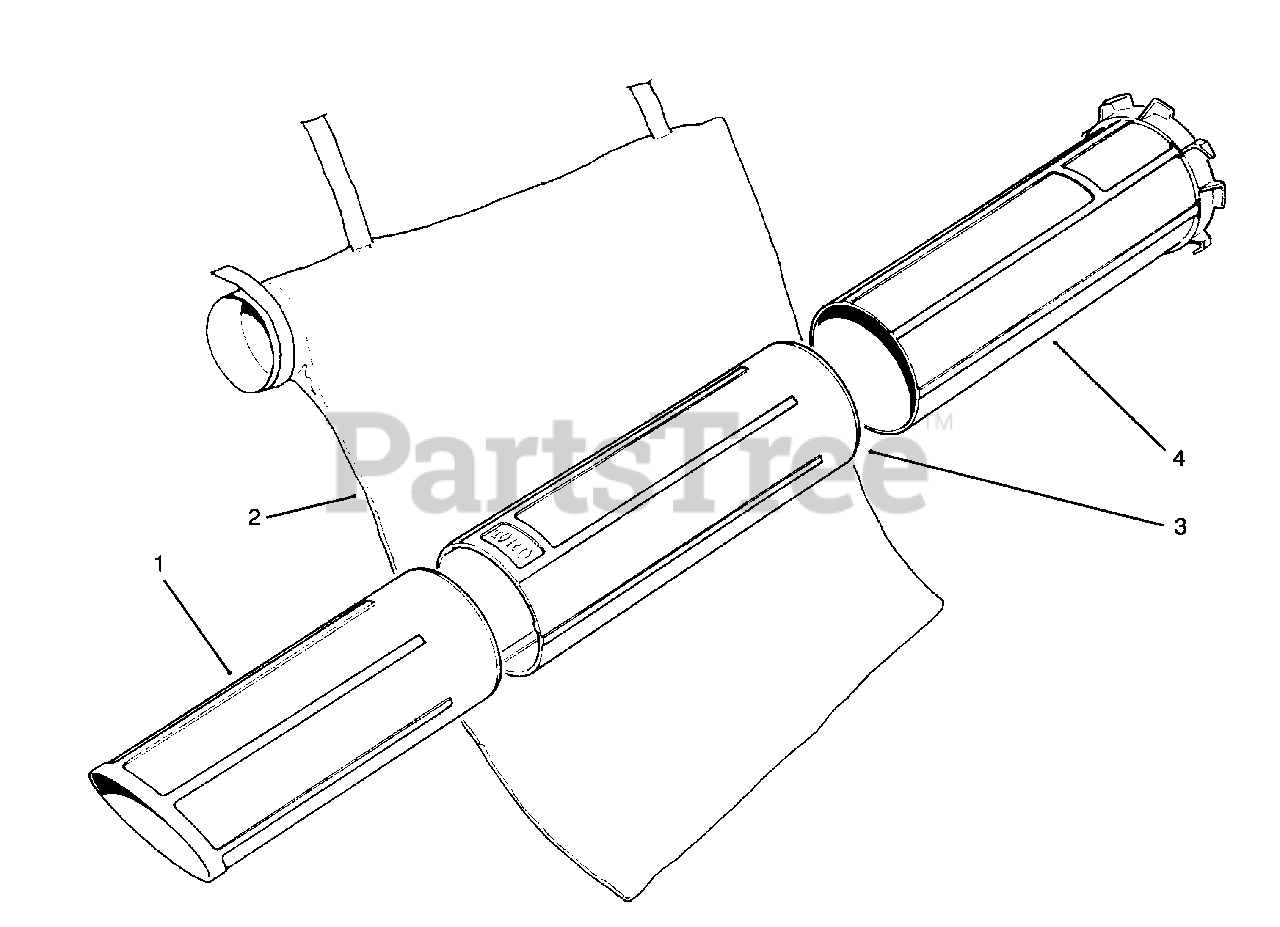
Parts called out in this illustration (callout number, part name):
1	Tube-Vacuum, Lower
2	Bag-Vacuum
3	Tube-Vacuum, Middle
4	Tube-Vacuum, Upper
